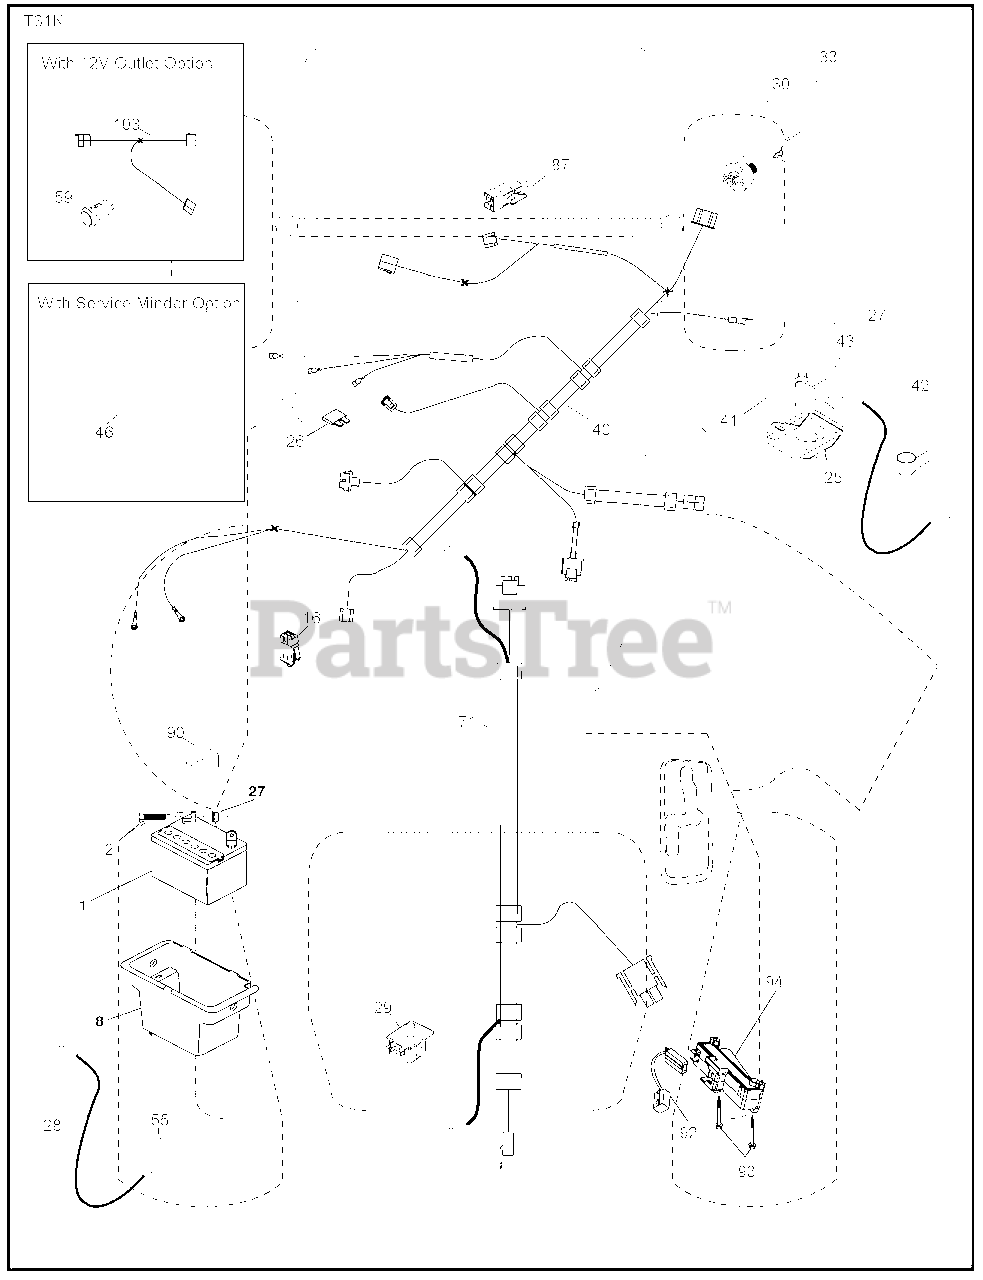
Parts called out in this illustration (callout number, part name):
2	Bolt Hex Hd 1/4-20 unc x 3/4
8	Box Battery
16	Switch Interlock
25	Cable Starter Battery 6 Ga. BL/Red 14.5
26	Fuse
27	Nut Keps Hex 1/4-20 unc
28	Cable Ground 18" Rear Battery Blk 6 Ga.
29	Switch Seat
30	Switch Ign
33	Key/Chain
40	Harness Ign
41	Screw 1/4-20 unc x 1/2
42	Cover Terminal Red
43	Solenoid
55	Screw 5/16-18 x 3/4
71	Harness Ign. Chass.
87	Switch Interlock Clutch
90	Cover Terminal
92	Harness Pigtail Reverse Switch
93	Screw Plastic 10-14 x 2.0
94	Modual Reverse ROS
